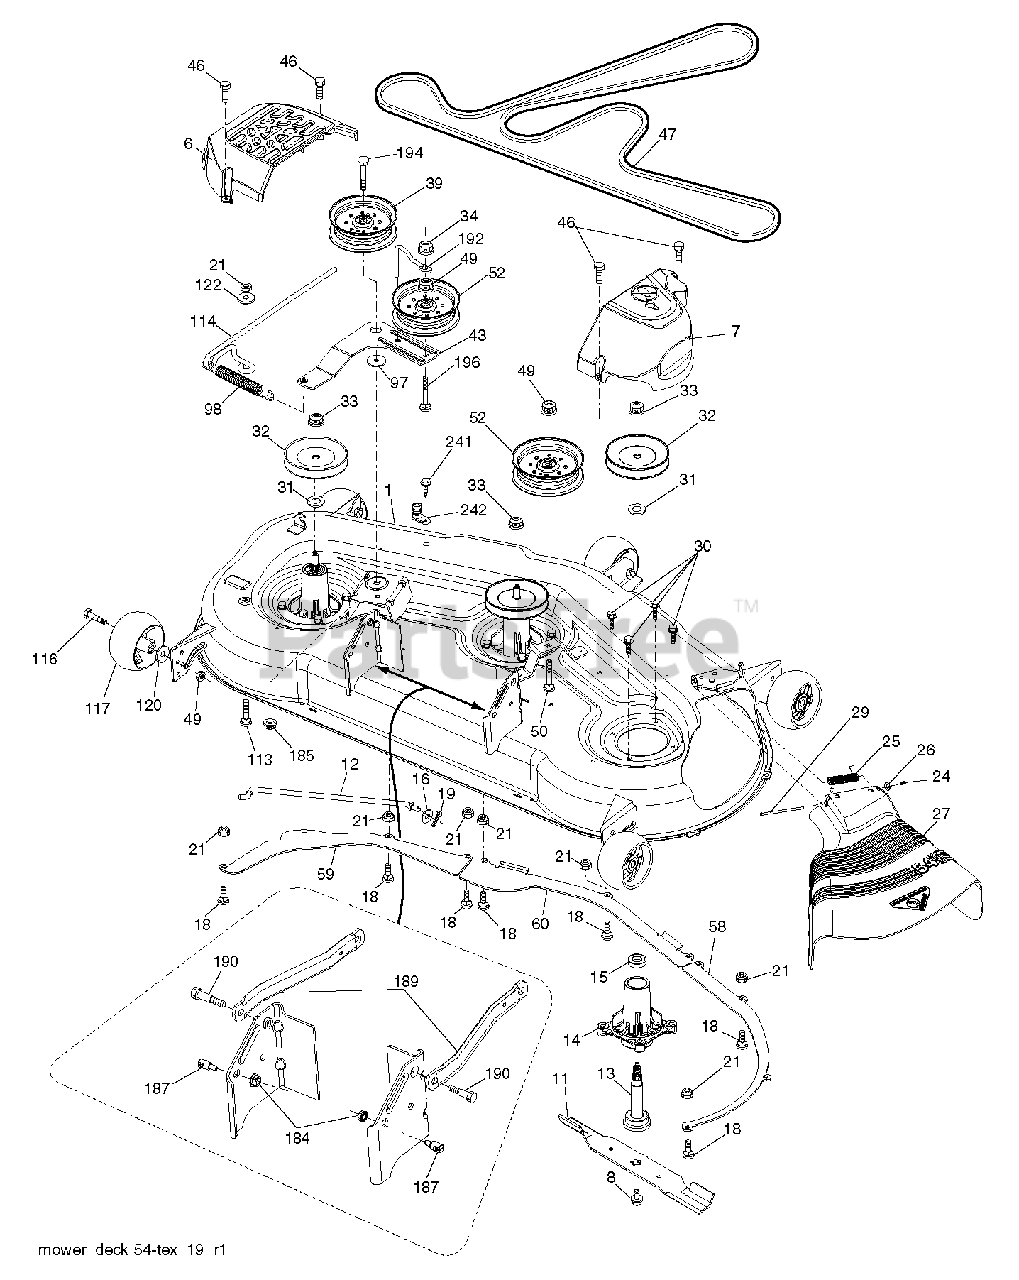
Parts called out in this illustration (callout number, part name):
1	DECK.WELDMENT.54"MS-666
6	COVER.MANDREL.LH.54"20
7	COVER.MANDREL.RH.54.20
8	BOLT.WASHER.ASM.7/16-2
11	BLADE, BAGGING 54''
12	ROD.ANTI.SWAY.48/54"TE
13	SHAFT ASM MANDREL
14	HOUSING MANDREL
15	BEARING
18	BOLT
19	PIN.COTTER.5/16.BOW TI
24	CAP-SLEEVE LT
25	SPRING, TORSION
26	NUT PUSH M
27	DEFLECTOR
29	HINGE ROD
30	SCREW, WASHER HEAD
32	PULLEY/MANDREL
33	NUT.FLANGE.LOCK.TOP
34	LOCKNUT
39	PULLEY.IDLER.4.50/HUB SPECIAL
43	ARM.IDLER
46	SCREW 1/4-20X5/8
47	BELT.DRIVE.54."2006
58	BAFFLE RIGHT
59	BAFFLE LEFT
60	BAFFLE CENTER 54" MOWER
98	SPRING.DRIVE.DECK.2006
113	BOLT CRT
114	ROD TENSION RELIEF
116	BOLT.SHOULDER.3/8-16X3-5/8
117	WHEEL. GUAGE RALLY
120	WASHER
122	BUSHING
184	NUT LOCK HEX FLANGE 5/16-18
185	NUT.LOCK.FLANGE.7/16
187	STUD.FASTNER.W/D.ANTI-
189	ARM.SUSPENSION.MOWER
190	BOLT.SHOULDER
192	KEEPER.BELT.IDLER.54"T
194	BOLT.CARR.SQNK.7/16
242	PORT.WASHOUT
